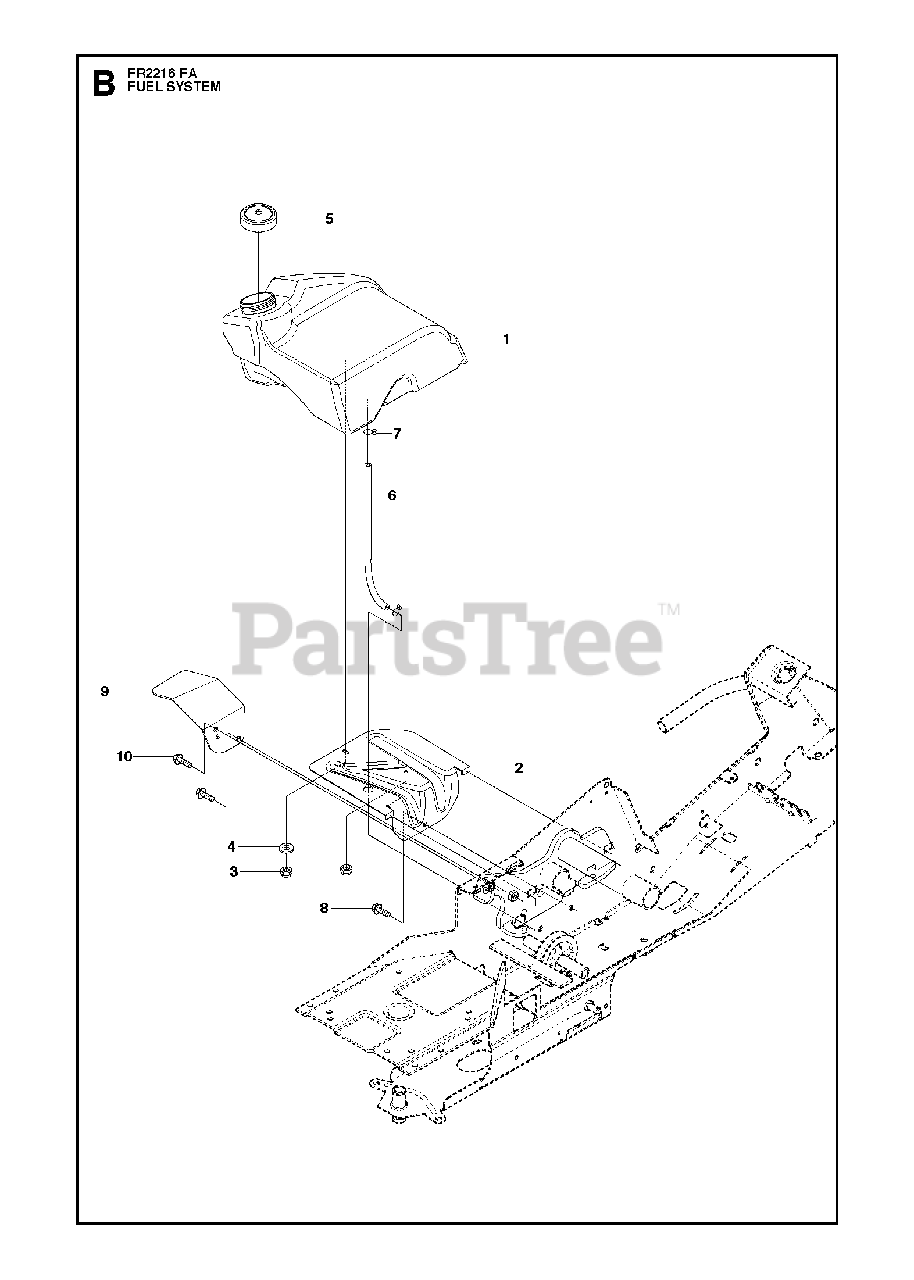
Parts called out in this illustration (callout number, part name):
3	LOCKNUT M6
4	WASHER
10	SCREW M10X25
